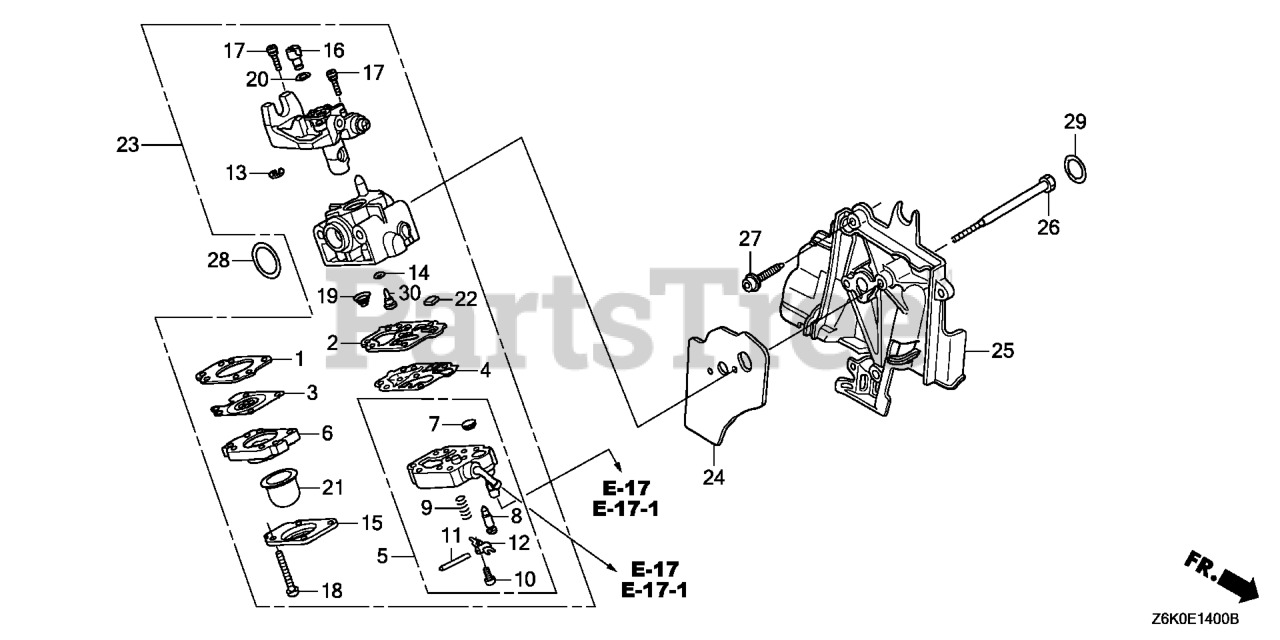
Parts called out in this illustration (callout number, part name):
1	GASKET, METERING DIAPHRAGM
2	GASKET, PUMP (CARBURETOR NO.)
3	DIAPHRAGM ASSY., METERING
4	DIAPHRAGM, PUMP
5	BODY ASSY., PUMP
6	BODY ASSY., AIR PURGE
7	SCREEN, INLET (CARBURETOR NO.)
8	VALVE, INLET NEEDLE
9	SPRING, METERING LEVER
10	SCREW, METERING LEVER PIN
11	PIN, METERING LEVER
12	LEVER, METERING
13	RING, RETAINING
15	COVER, PRIMER PUMP
17	SCREW, THROTTLE COLLAR
18	SCREW, PUMP COVER
19	SPRING, PUMP
21	PUMP, PRIMER
22	FILTER, FUEL INLET (CARBURETOR NO.)
23	CARBURETOR ASSY. (WYB 50A)
24	GASKET, CARBURETOR
26	BOLT (5X53)
27	BOLT, SOCKET (5X16)
28	O-RING (14.8X2.4)
29	O-RING (12.3X2.4) (CARBURETOR NO.)
30	JET (#34) (CARBURETOR NO.)
30	JET (#35) (CARBURETOR NO.)
30	JET (#36) (CARBURETOR NO.)
